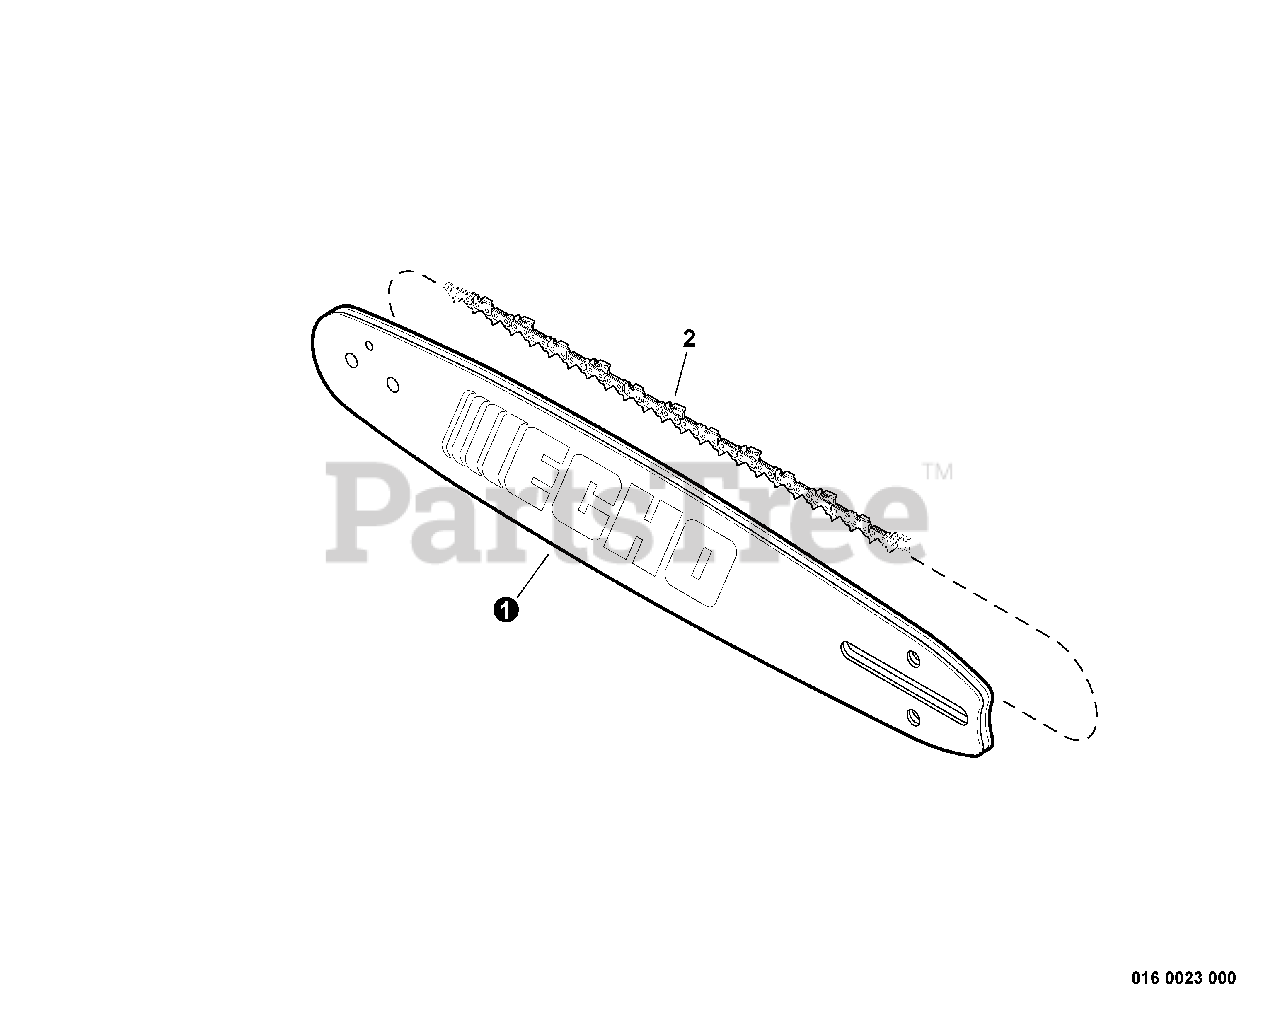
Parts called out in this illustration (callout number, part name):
1	GUIDE BAR, 16" PRO-LITE 0.325
1	GUIDE BAR, 18" PRO-LITE 0.325
1	GUIDE BAR, 20" PRO-LITE 0.325
1	GUIDE BAR, 16" DOUBLE-GUARD
1	GUIDE BAR, 18" DOUBLE-GUARD
1	GUIDE BAR, 20" DOUBLE-GUARD
1	GUIDE BAR, 16" MICRO-LITE PRO
1	GUIDE BAR, 18" MICRO-LITE PRO
2	SAW CHAIN 16"
2	SAW CHAIN 18"
2	SAW CHAIN 20"
